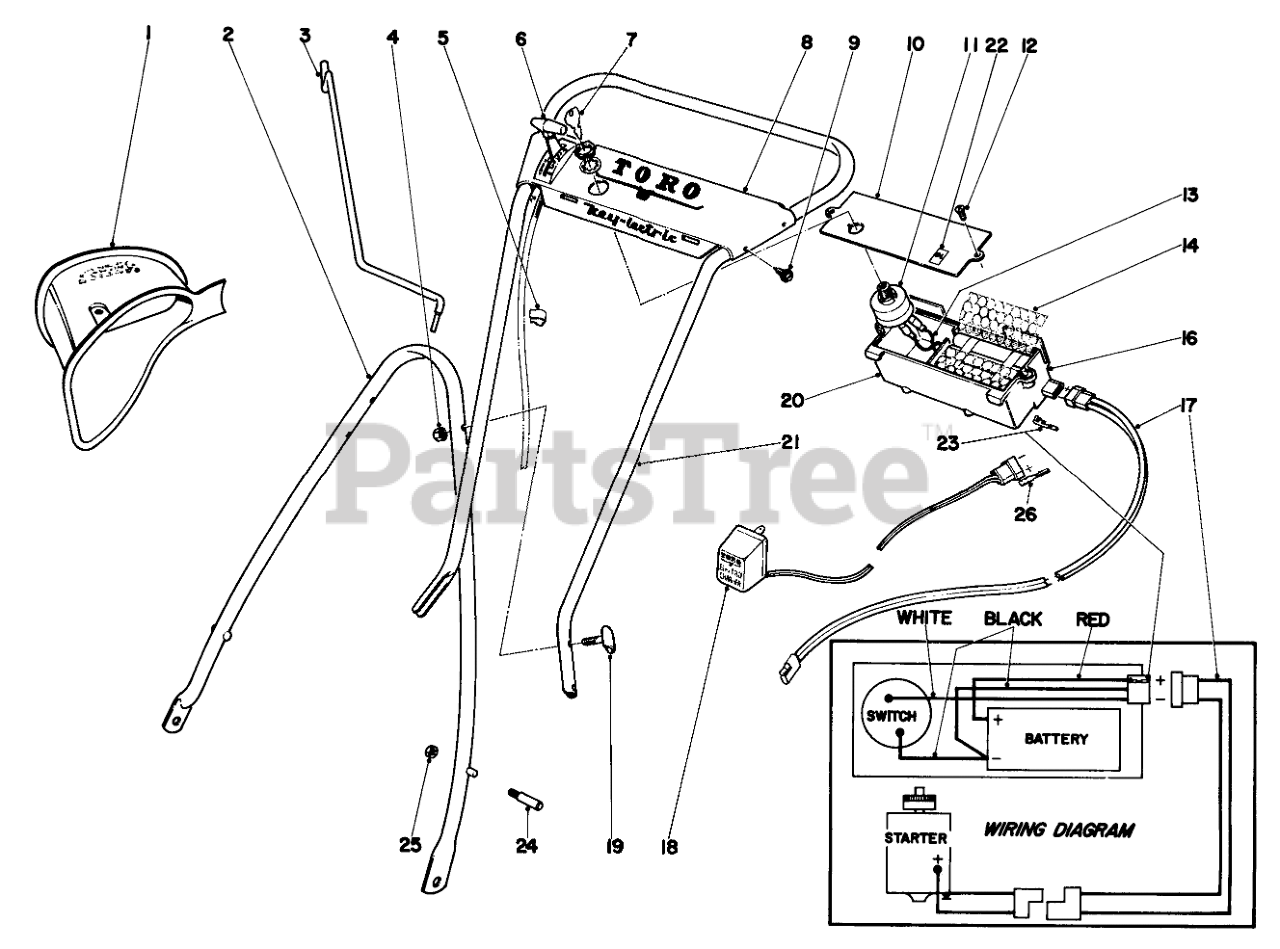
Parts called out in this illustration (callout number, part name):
1	Attachment Bag
2	Handle-Lower
3	GRASS BAG HANGER
4	Nut
5	CONTROL WIRE CLIP
6	Throttle Control
7	Key
8	Plate, Escutcheon
9	SCREW-HWHTF
10	Cover, Battery Pack
11	Switch, Starter
12	Self Tapping Screw
13	Lead Wire
14	Spacer-Battery
16	Container Battery Pack
17	Harness
18	Charger, Battery
20	Battery Pack Assy. (Incl. Ref. 13 thru 16)
21	Handle-Upper
22	Decal
23	Terminal
24	Handle Pin
25	Nut
26	PLUG TERMINAL
